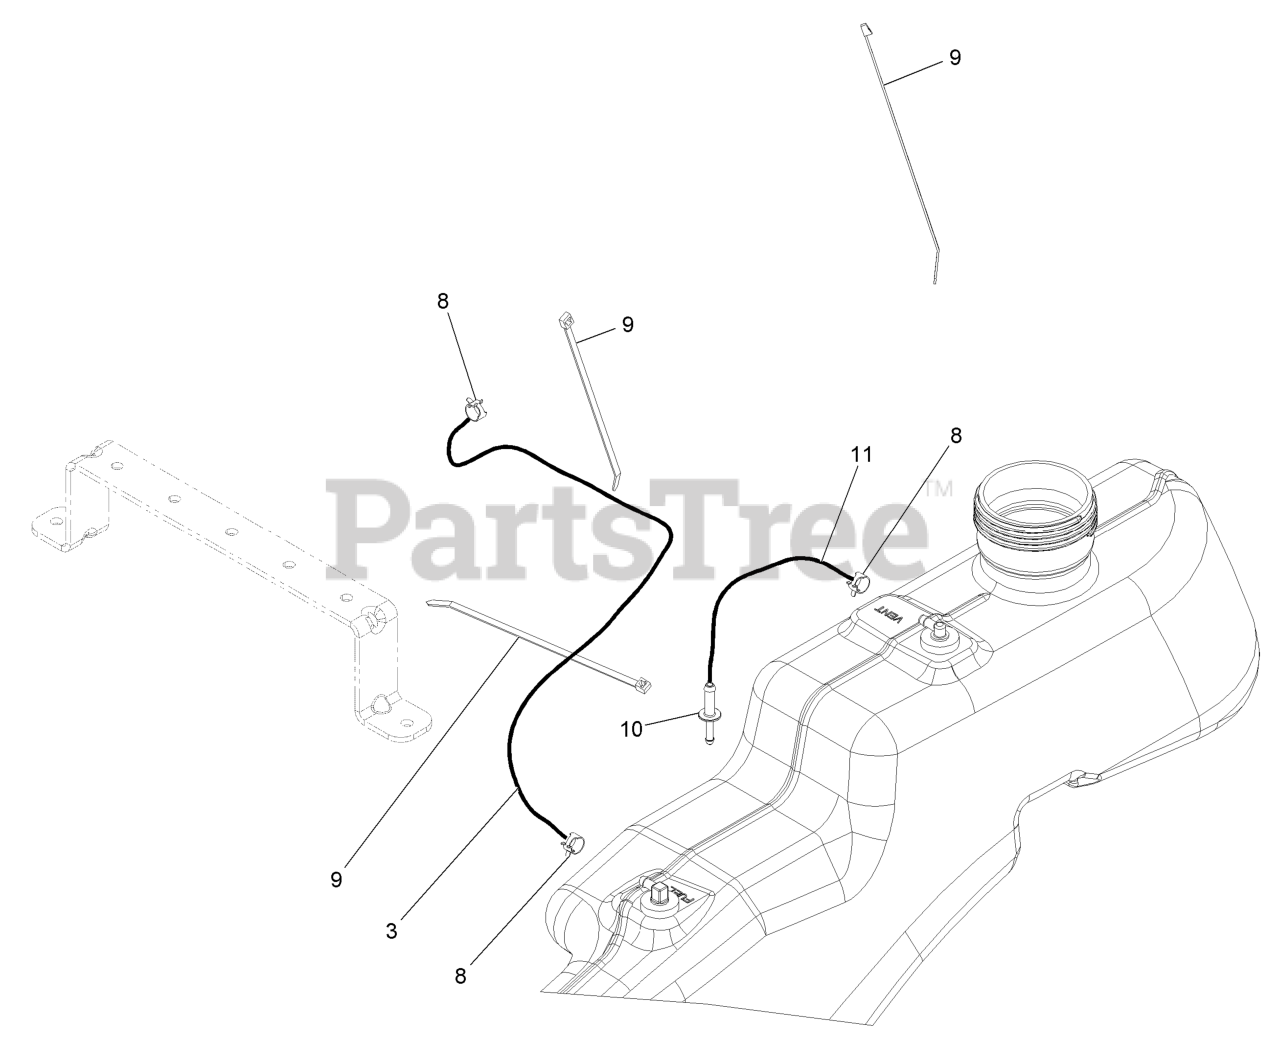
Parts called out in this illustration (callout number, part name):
3	HOSE-FUEL
8	CLAMP-HOSE
9	TIE-CABLE
10	ADAPTOR-ORIFICE
11	HOSE-FUEL
